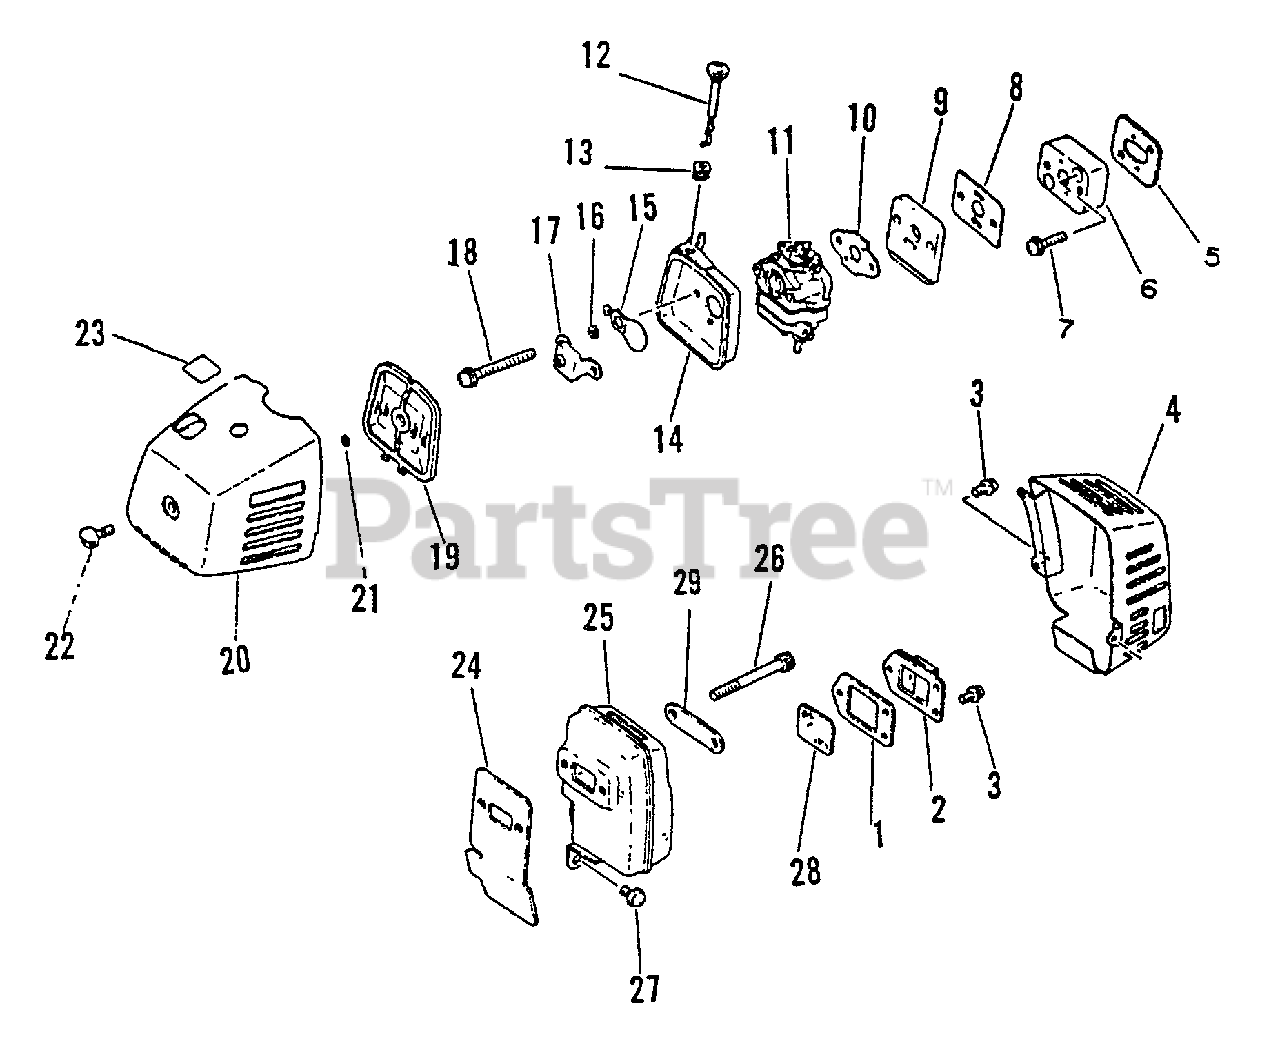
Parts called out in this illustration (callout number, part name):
1	GASKET, EXHAUST
2	GUIDE, EXHAUST
3	SCREW - 4X8
4	COVER, EXHAUST
5	GASKET, INTAKE
6	INSULATOR, INTAKE
7	SCREW - 5X20
8	GASKET, INTAKE
9	PLATE
10	GASKET, INTAKE
11	CARBURETOR
12	ROD, CHOKE
14	CASE, AIR FILTER
15	SHUTTER, CHOKE
16	WASHER - 5
17	PLATE, PREVENT
18	SCREW - 5X50
19	FILTER, AIR
20	AIR FILTER COVER ASSY
21	O-RING - 4
23	LABEL - CHOKE
24	GASKET, EXHAUST
25	MUFFLER
26	SCREW - 5X55
27	SCREW - 5X10
28	SCREEN, SPARK ARRESTOR
